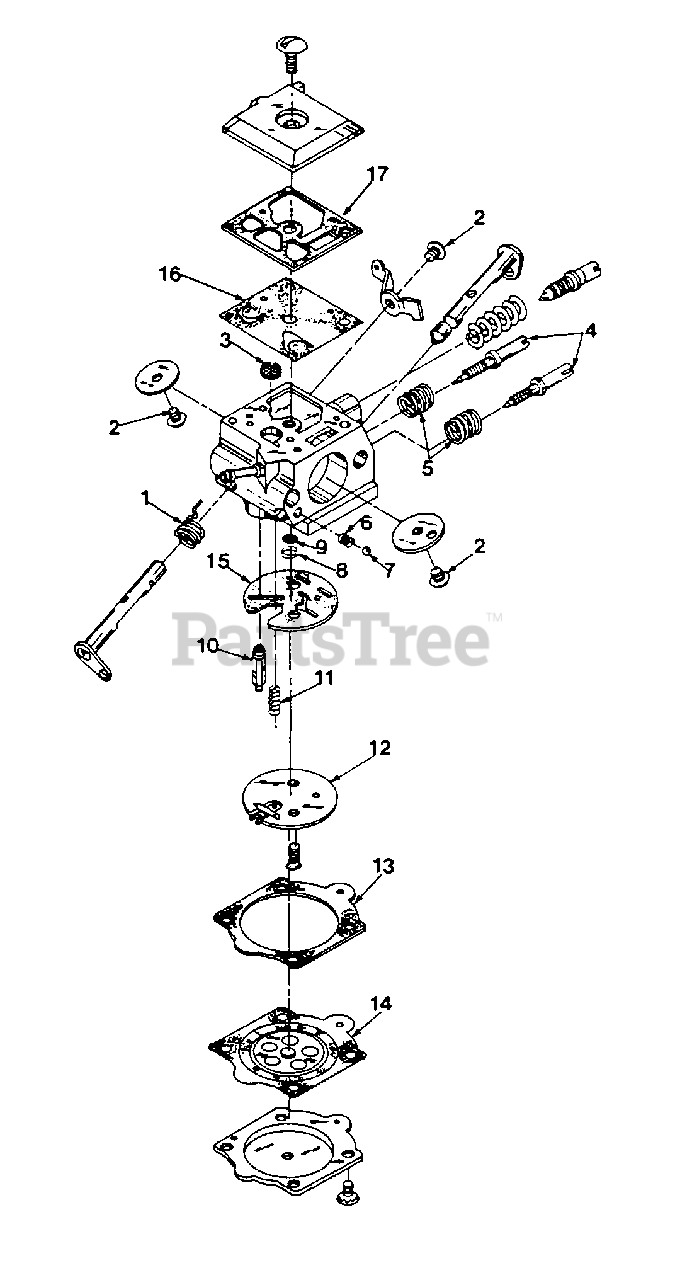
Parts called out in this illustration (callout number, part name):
1	Repair Kit
2	Repair Kit
3	Repair Kit
4	Repair Kit
5	Repair Kit
6	Repair Kit
7	Repair Kit
8	Repair Kit
9	Repair Kit
10	Repair Kit
11	Repair Kit
12	Repair Kit
13	Repair Kit
14	Repair Kit
15	Repair Kit
16	Repair Kit
17	Repair Kit
